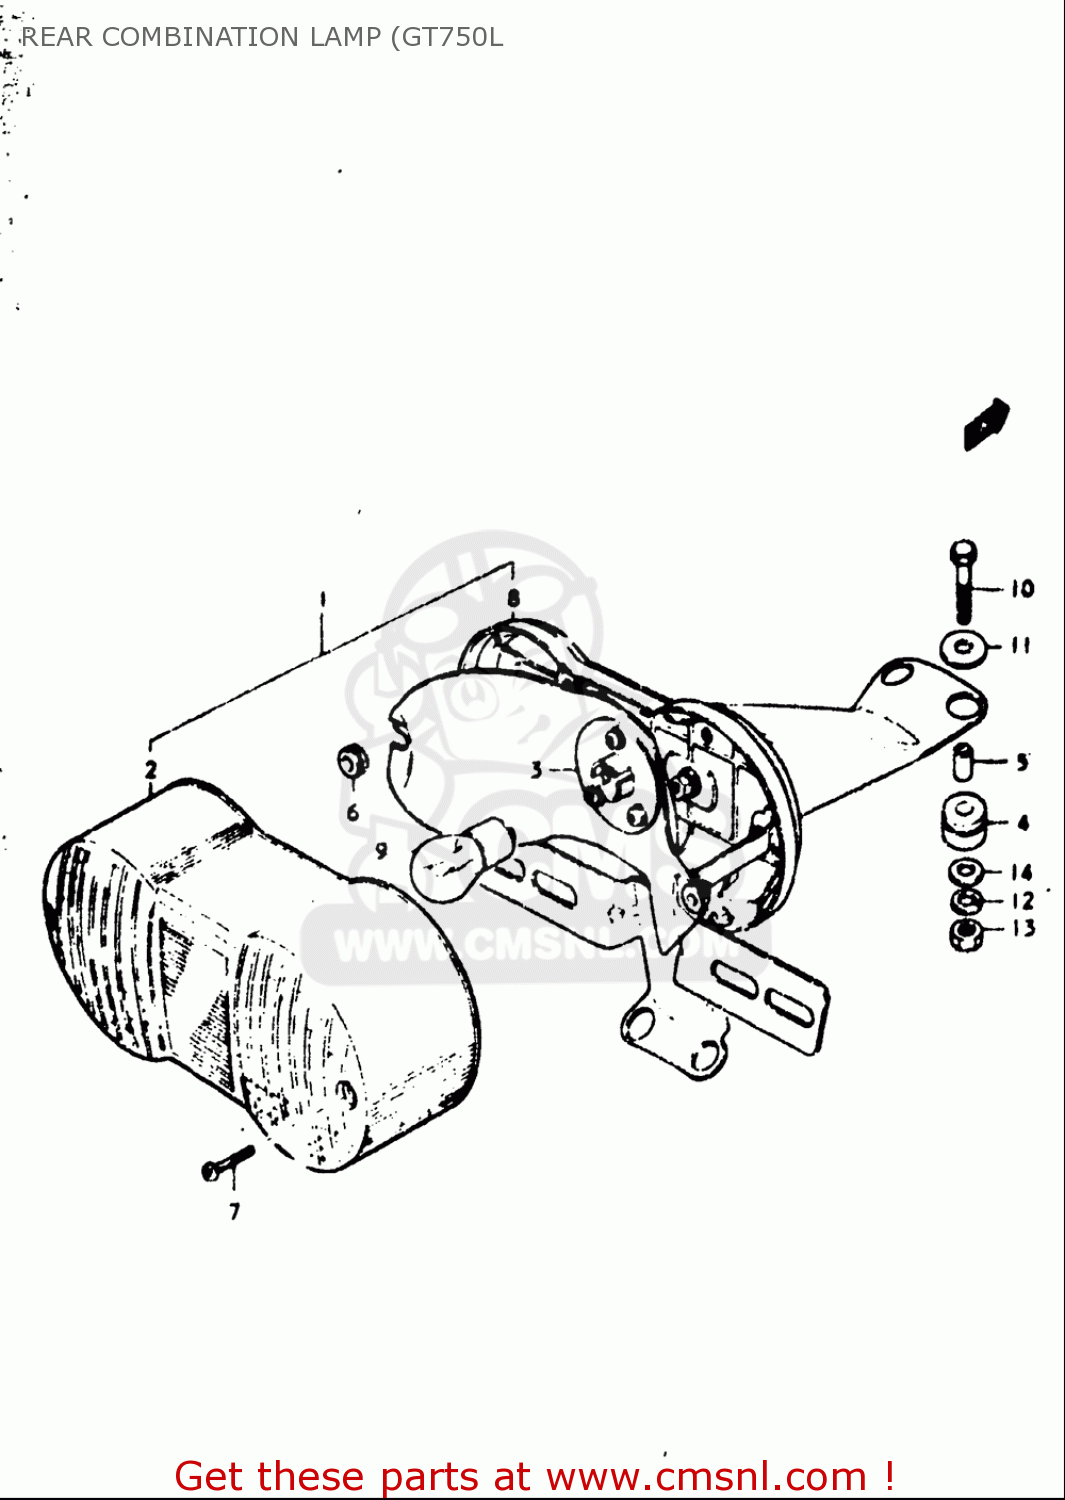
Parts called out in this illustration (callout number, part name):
2	LENS,RR COMBINATION LAMP
4	CUSHION
5	SPACER
6	CUSHION
7	SCREW
8	HOUSING,RR COMBINATION LAMP
9	BULB(12V23W)
10	BOLT
11	WASHER(6.5X20X1.6)
12	WASHER,LOCK
13	NUT
14	WASHER
